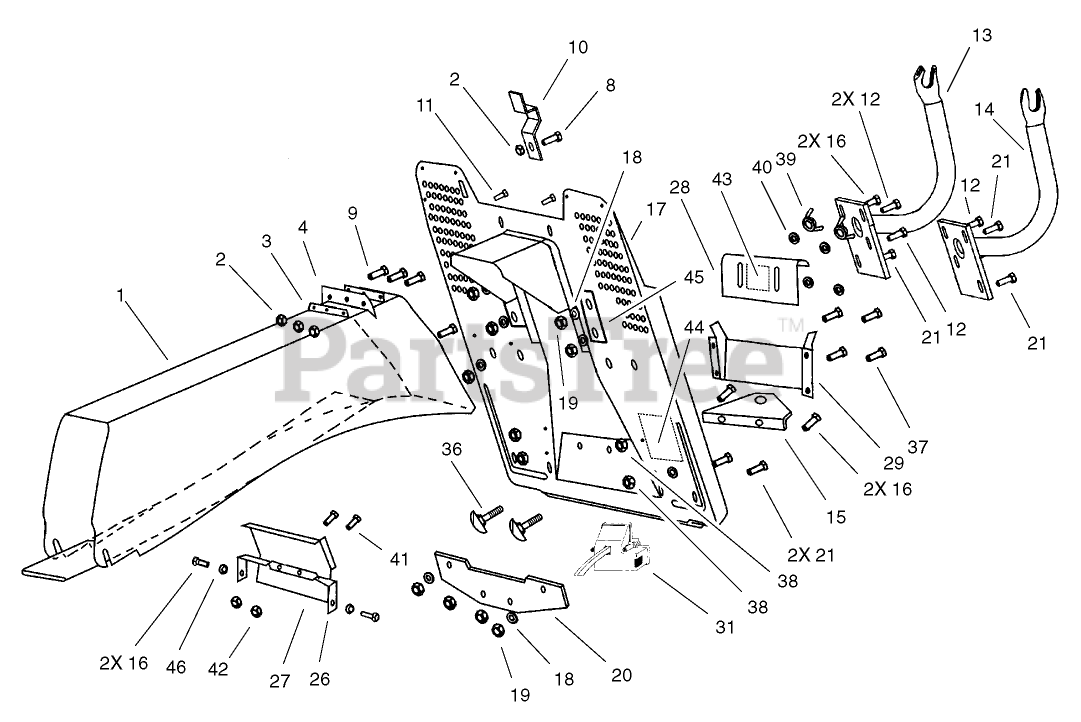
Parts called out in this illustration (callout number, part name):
1	TUNNEL
2	NUT-HEX
3	PLATE-SUPPORT
4	SEAL-RUBBER
9	SCREW-SFH
10	COVER-SWITCH
11	BOLT-CARRIAGE
13	SUPPORT-COLLECTOR, RIGHT
14	SUPPORT-COLLECTOR, LEFT
15	HITCH-TOW
16	SCREW-HEX
17	COLLECTOR PLATE ASM
18	WASHER-FLAT
19	NUT-LOCK, NI
20	SUPPORT-HITCH, TOW
21	SCREW-HEX
26	BRACKET-SHIELD, PROTECTIVE
27	SHIELD-PROTECTIVE
28	Shield-Adjustable
31	OVERLOAD SWITCH ASM
37	SCREW-HH
38	NUT-LOCK
39	NUT-WING
40	WASHER-FLAT
41	BOLT-CARRIAGE
42	NUT-LOCK
43	DECAL-POSITION, BAGGING
44	DECAL-BYPASS, HYDRO
45	Plate-Reinforcing
